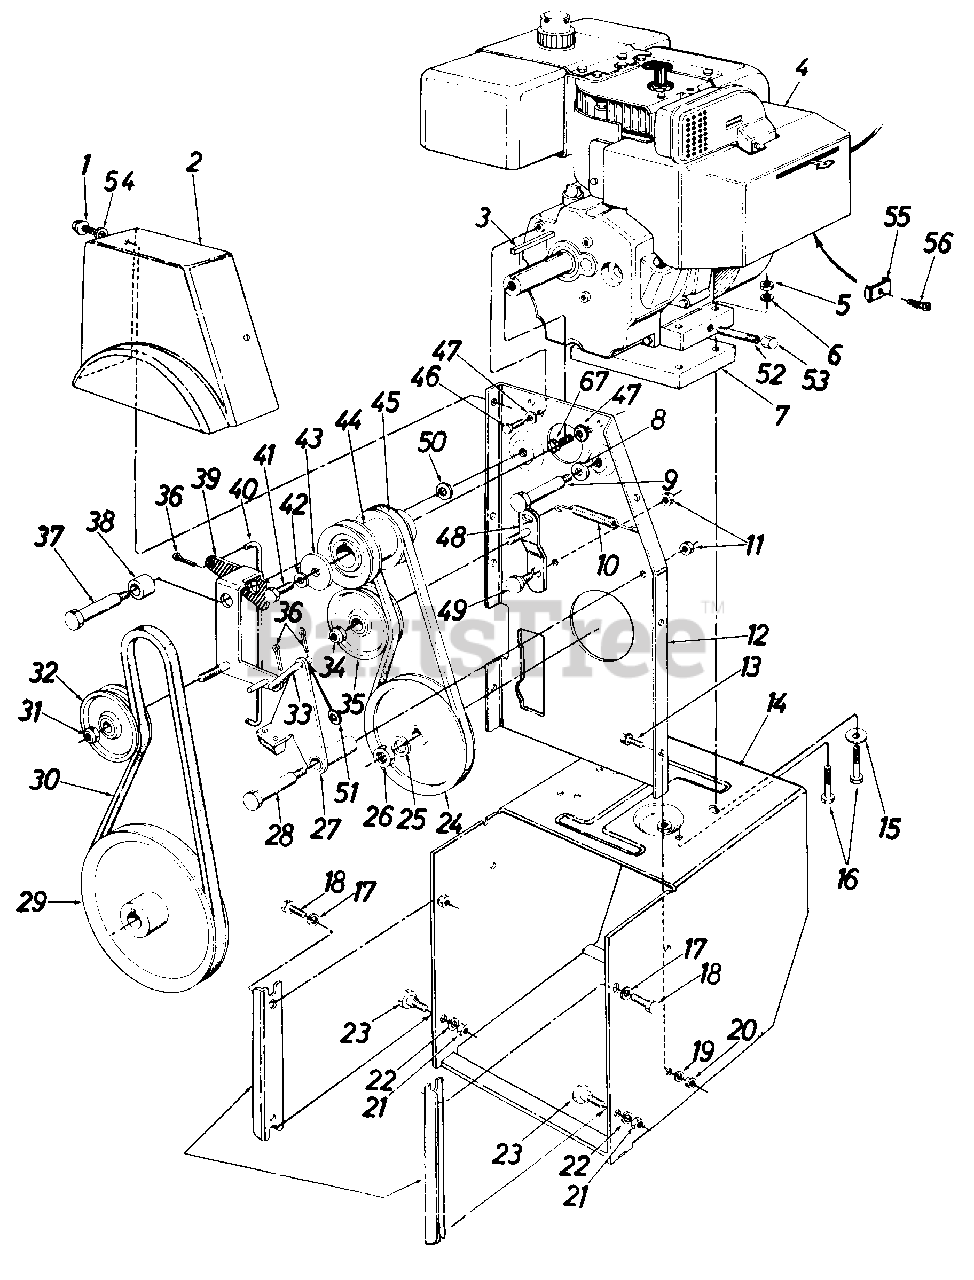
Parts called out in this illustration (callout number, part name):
1	Hex Wash. Self-Tap Scr. 5/16-24 x .50" Lg.
2	Belt Cover
3	Sq. Key 1/4" X 1.50" Lg.
4	Engine
5	Hex Nut 5/16-18 Thd.
6	L-Wash. 5/16" Scr.
7	Engine Spacer Ass'y.
8	Bell-Wash. .40 I.D. x .88 O.D.
9	Stud 3/8-16 x 3.37" Lg.
10	Ext Spring 38 O.D. x 3.18" Lg.
11	Hex Cent. L-Nut 3/8-16 Thd.
12	Engine Brkt. Ass'y.
13	Hex Sems Scr. 5/16-18 x .75" Lg.
14	Frame Ass'y.
15	Fl-Wash. .345 I.D. x .75 O.D. x .060
16	Hex Bolt 5/16-18 x 2.50" Lg.
17	L-Wash. 3/8" I.D. H.D.
18	Pilot Scr. 3/8-16 x .88" Lg.
19	L-Wash. 5/16" I.D.
20	Hex Nut 5/16-18 Thd.
21	Hex Nut 3/8-16 Thd.
22	L-Wash. 3/8" I.D. H.D.
23	Shld. Bolt .498" Dia. x .340" Lg.
24	V-Pulley .628 I.D. x 7.50 O.D.
25	L-Wash. 518" I.D.
26	Hex Ins. Jam L-Nut 5/8-18 Thd.
27	Brake Brkt. Ass'y.
28	Shld. Bolt .498" Dia. x 2.00" Lg.
29	V-Pulley .875 I.D. x 10.12 O.D.
30	"V"-Belt 1/2 " X 45.0" Lg.
31	Hex Ins. Jam L-Nut 3/8-24 Thd.
32	Fl-Idler w/Flanges 3.0 O.D.
33	Brake Linkage Ass'y.
34	Hex Ins. Jam L-Nut 3/8-24 Thd.
35	Flat Idler Pulley
36	Int. Cot. Pin 5/16" Dia.
37	Shld. Bolt .625 Dia. x 2.750" Lg.
38	Spacer .75 O.D. x 1.00" Lg.
41	Hex Bolt 3/8-24 x 1.25" Lg.
42	L-Wash. 3/8" I.D. H.D.
43	Fl-Wash.
44	Engine Pulley
45	"V"-Belt 3/8 x 35.5 Lg.
46	Hex Bolt 5/16-24 x .62" Lg.
47	Bell-Wash. .345 I.D. x .88 O.D. x .060
48	Drive Idler Brkt. Ass'y.
49	Shld. Bolt .625" Dia. x 170" Lg.
50	Bell-Wash. .40 I.D. x 1.12 O.D.
51	Fl-Wash. .34 I.D. x .750 O.D. x .05
52	Pipe Nipple 1/2" Pipe Thd. x 3.00" Lg.
53	Hex Bolt 1/4-18 Pipe Thd.
54	Fl-Wash. .340 I.D. x .62 O.D. x .62
55	Throttle Control Wire Clamp
56	Hex Sems Scr. #10-32 x .62" Lg.
